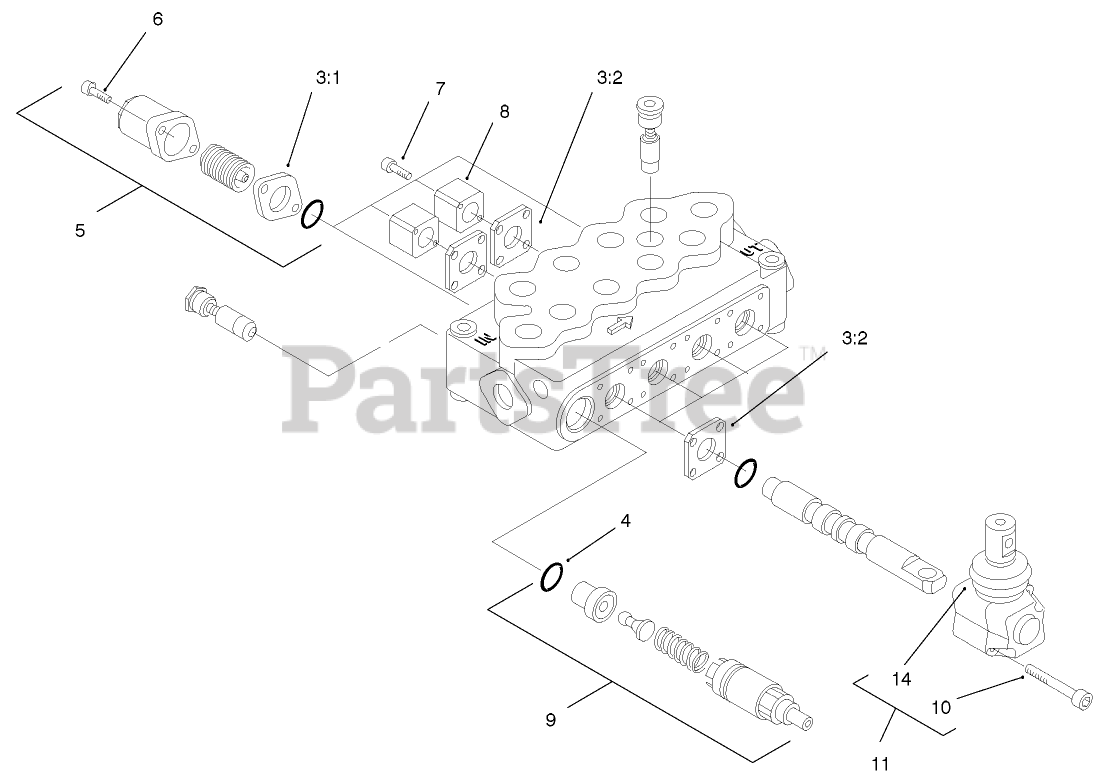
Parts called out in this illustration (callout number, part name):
3	SEAL KIT
3:1	GASKET
3:2	GASKET
5	HIGH FORCE SPRING KIT
6	SCREW-CAP, END
8	BLOCK-MOUNT, SWITCH
9	VALVE-RELIEF
11	OPERATOR ASM
